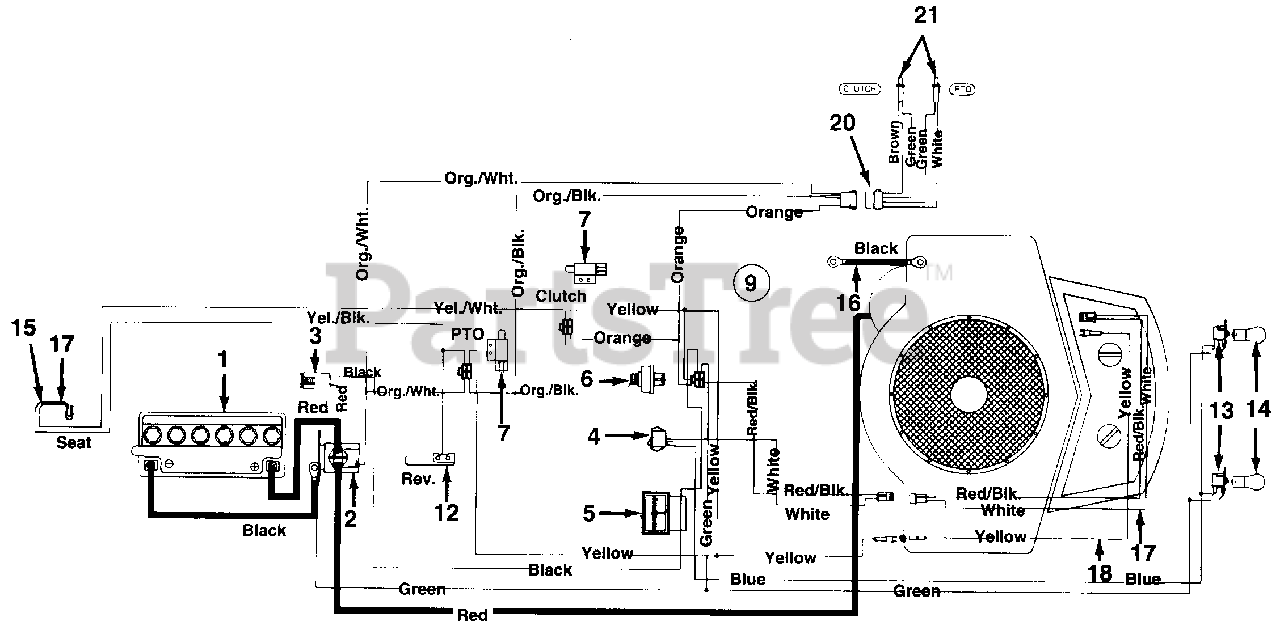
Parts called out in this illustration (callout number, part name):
1	Battery
2	Solenoid
3	Fuse 7.5 Amps
4	Light Switch
5	Ammeter
6	Ignition Switch
7	Safety Switch
9	Wire Harness
12	Safety Switch (Reverse)
13	Socket
14	Bulb (Headlight)
15	Safety Switch (Seat)
16	Ground Wire 7.5" Lg.
17	Safety Switch (Seat)
18	Harness Adapter
20	Monitor Harness
21	Monitor Bulb
